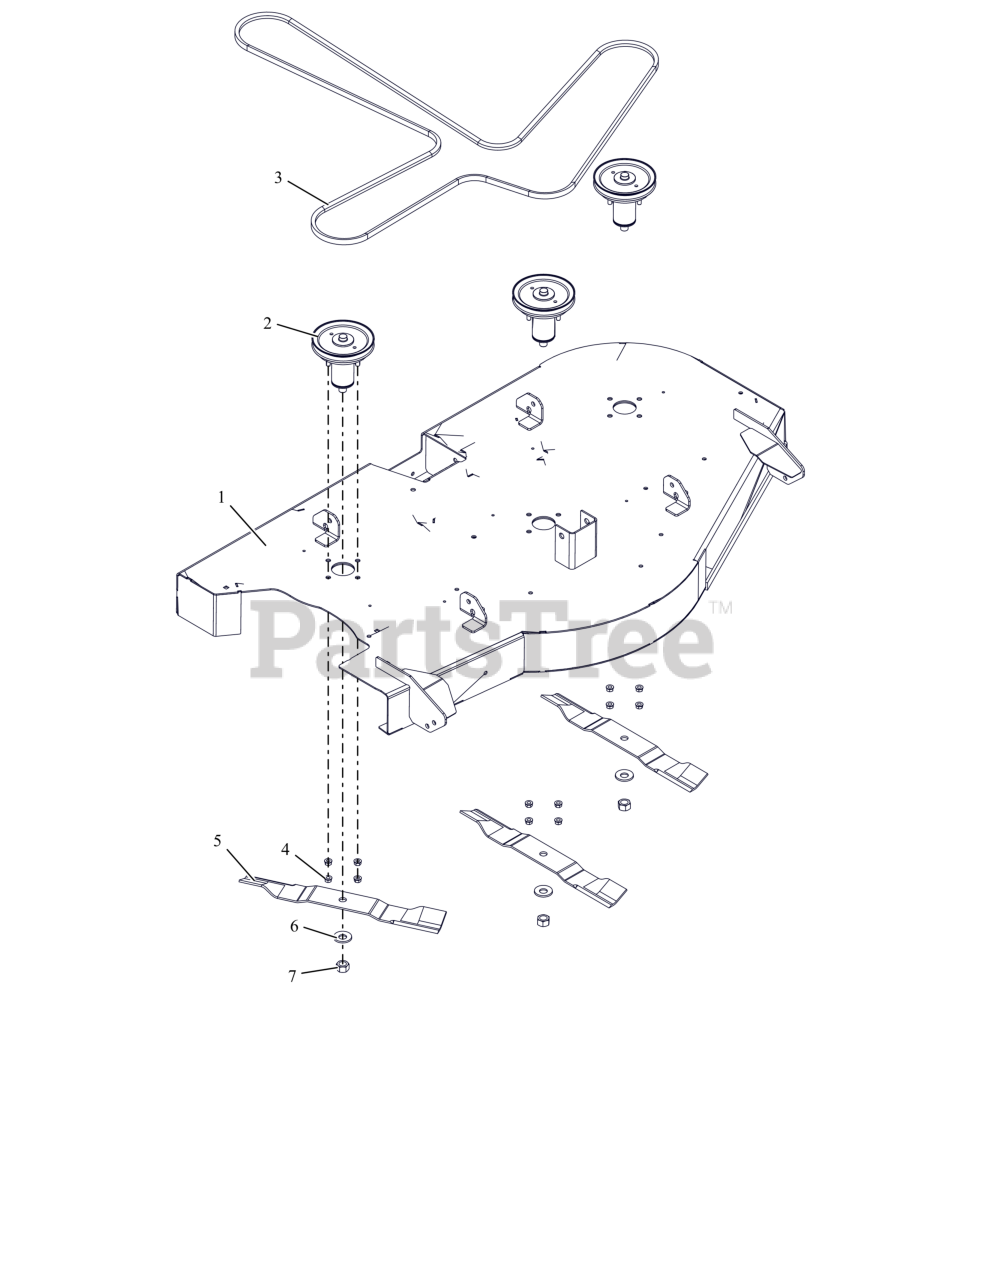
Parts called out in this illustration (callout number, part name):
1	KIT, 52" ZT DECK W/DECALS
2	KIT- DECK SPINDLE ASSM- 52"
3	V-BELT, HA-WRAPPED
4	NUT,LK-CTR-FLG .31-18 GF ZCC
5	BLADE, 18" - 30 DEG .5 OFFSET
6	WSHR-BLVL .669X1.535X.138
7	NUT-STD .625-18 ZCC
